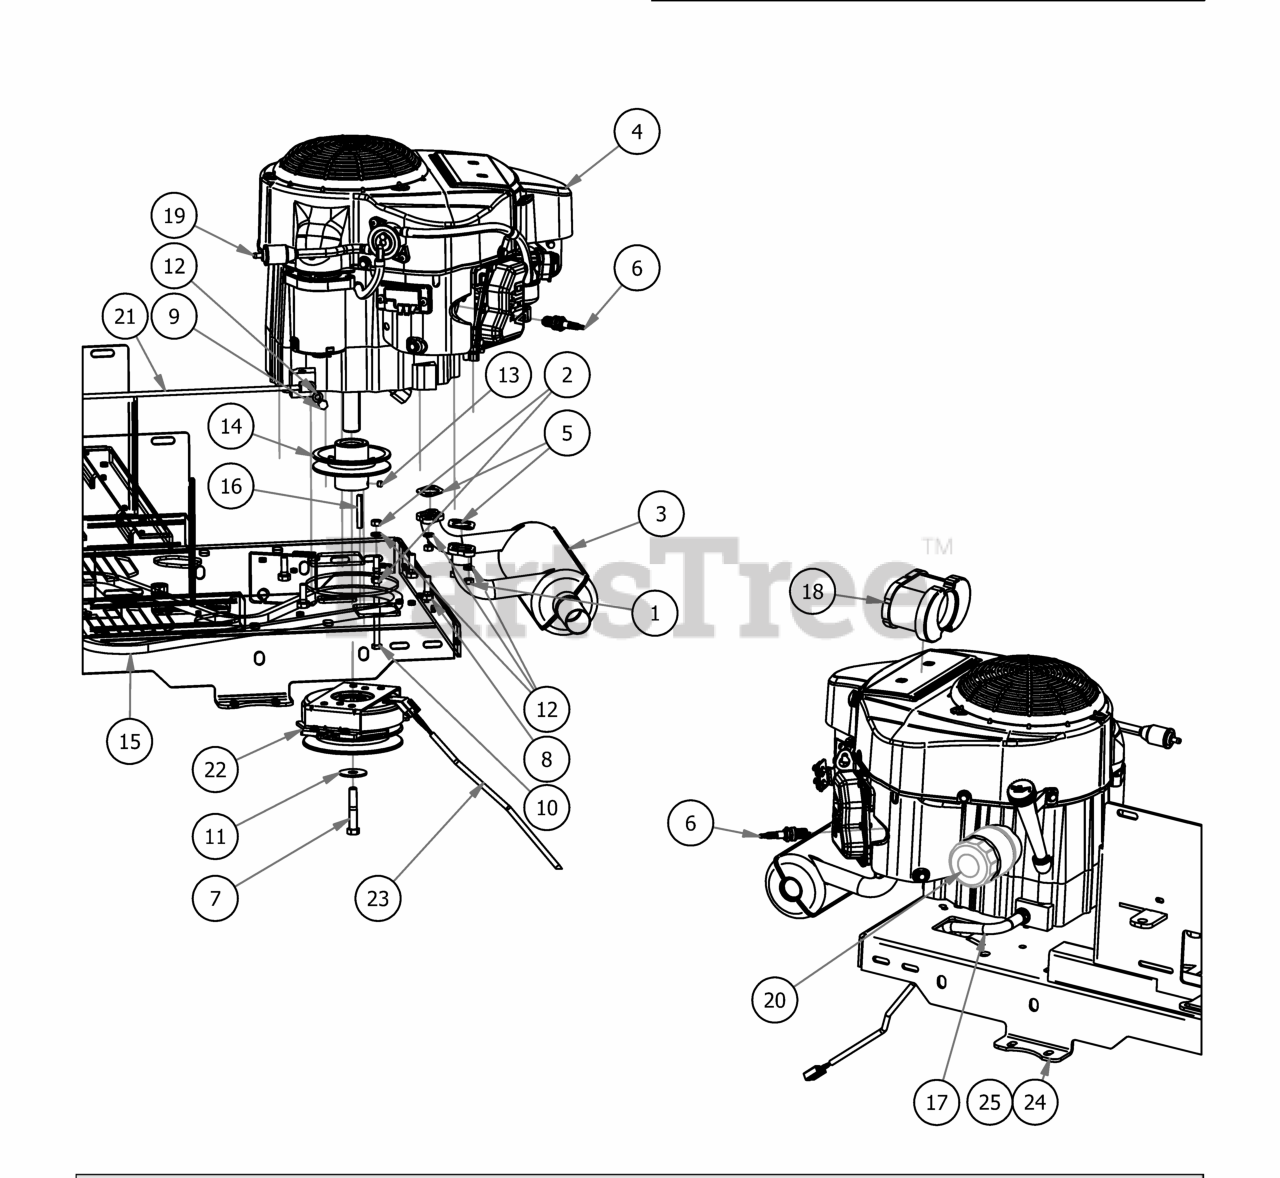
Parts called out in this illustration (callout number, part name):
1	M8-1.25 Zinc Nut
3	Kawasaki Muffler 1251
4	Kawasaki Engine-FR730V
5	Exhaust Gasket
6	Spark Plug - Kawasaki
7	7/16"-20 x 2.5" Hex Bolt Gr. 8
8	3/8 x 1 1/8 bolt
9	M8x1.20x20MM Hex head bolt
10	5/16-18 x 5-1/2 GR 5 Hex Bolt
11	1/2" Belleville Washer
12	5/16" Lock Washer
13	5/16 Set Screw
14	4 3/4 Motor Pulley
16	1/4 x 2 Square key Stock
17	Oil drain Hose
18	Kawasaki Air Filter
19	Universal Inline Fuel Filter
20	Kawasaki Oil Filter
21	24" Black Ground Cable
23	Clutch Pigtail
24	2017 MZ/ZT 54"-60" Frame
25	2017 MZ/ZT 42"-48" Frame
